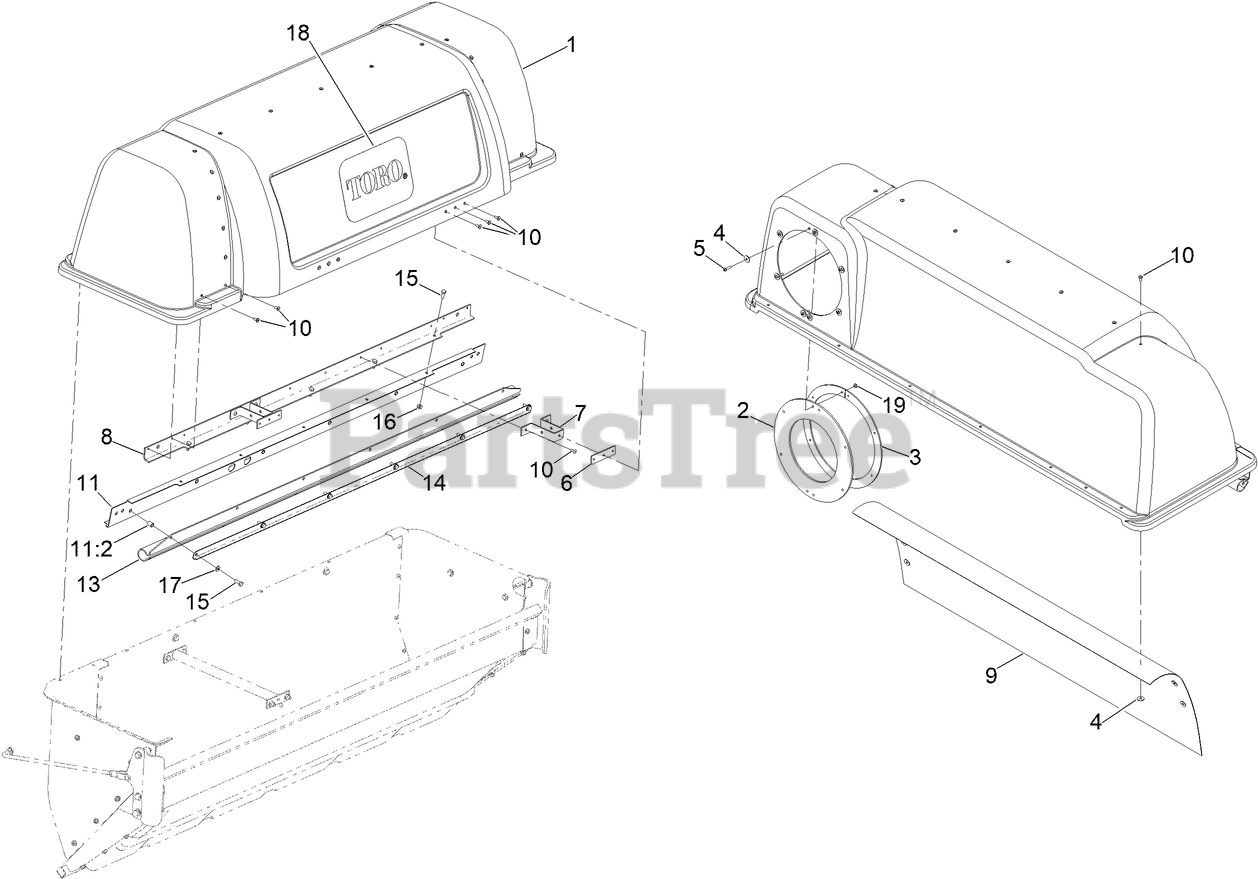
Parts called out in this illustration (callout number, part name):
1	HOOD ASM
2	SEAL-TUBE
3	CLAMP-SEAL
4	WASHER-FLAT
5	SCREW-PPH
6	PLATE-LATCH, REINFORCEMENT
7	BRACKET-MOUNT
8	SUPPORT-SCREEN
9	SCREEN-BAGGER
10	RIVET-BLIND
11	REAR CROSSMEMBER ASM
11	CROSSMEMBER-REAR
11:2	NUT-CLINCH
13	SEAL-DOOR HINGE
14	STRAP-HOLD DOWN
15	SCREW-HH
16	NUT-HF
17	WASHER-FLAT
18	DECAL
19	NUT-LOCK, NI
